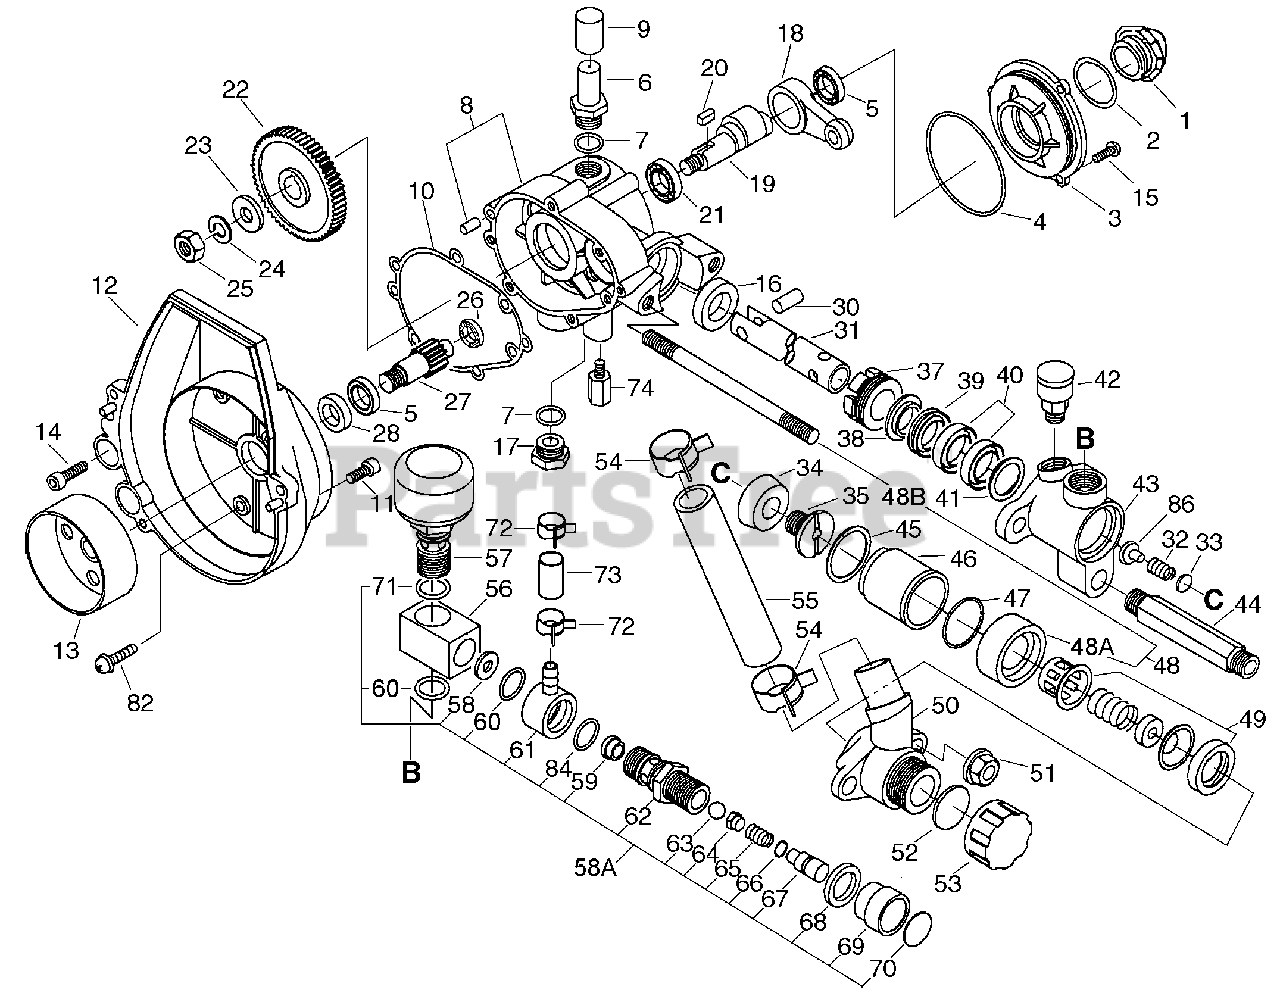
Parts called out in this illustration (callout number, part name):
1	GAUGE, OIL
3	LID, GEAR CASE
5	BEARING, BALL - 6001
8	PUMP BODY ASSY
11	SCREW - 5X18
12	COVER, FAN
13	DRUM, CLUTCH
14	SCREW - 5X25
15	SCREW - 4X12
16	SEAL, OIL
17	CAP, DRAIN
18	ROD, CONNECTING
19	CRANKSHAFT
21	BEARING, BALL - 6201
22	GEAR - SPUR
23	WASHER - 8
24	LOCKWASHER - 8
26	BEARING, BALL - 609
27	SHAFT, PINION
28	SEAL, OIL
30	PIN, PISTON
31	PLUNGER ASSY
32	VALVE SPRING
33	DISK, VALVE
34	SEAL, PISTON
35	SEAT, VALVE
37	NUT - GLAND
38	SEAL, GREASE
39	SEAL, GREASE
40	SAEL SET
42	CUP, GREASE
43	CYLINDER
48	VALVE CASING ASSY
48A	CASING, VALVE
49	VALVE ASSY
50	PIPE, INTAKE
52	GASKET, DRAIN
53	CAP, DRAIN
55	HOSE - SUCTION
56	CONNECTOR
57	CHAMBER, AIR
58A	REGULATOR ASSY
59	SEAT, VALVE
60	O-RING - 16
61	CASING, VALVE
62	CASING, SPRING
63	VALVE, BALL
64	SEAT, SPRING
66	O-RING - 7
67	SEAT, SPRING
69	CAP, REGULATOR
70	LABEL - REGULATOR
71	O-RING - 12.5
73	HOSE - RETURN
82	SCREW - 5X25
86	SEAT, SPRING
